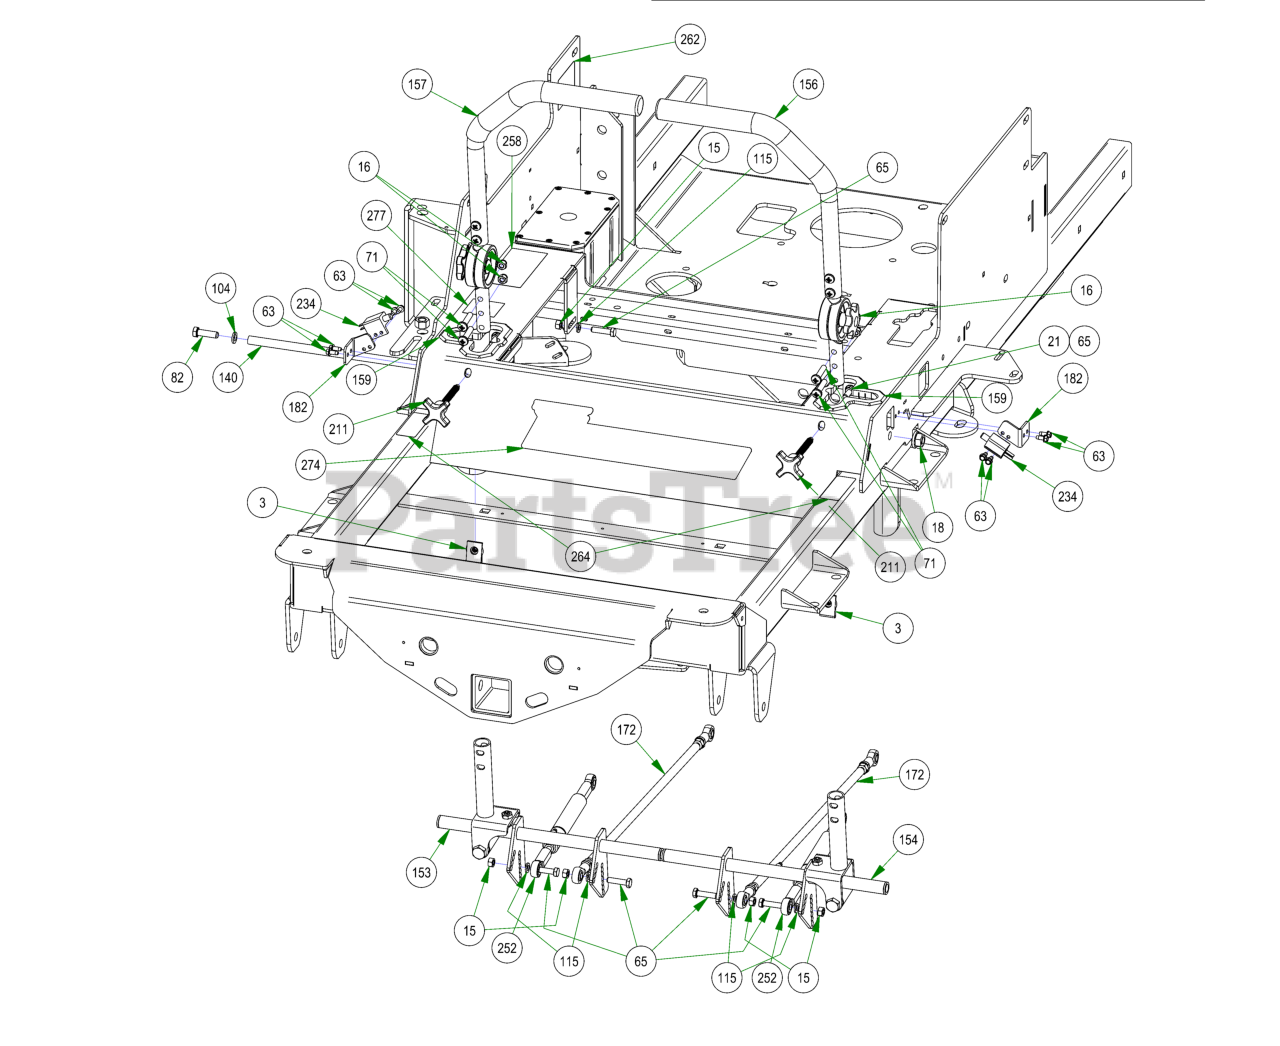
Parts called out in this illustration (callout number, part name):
3	Extruded Nut 3/8"-16 3/4" Hole Center With Patch
11	3/8-16 HEX NUT ZINC
15	5/16-18 HEX NUT ZINC
16	5/16-18 NYL INS L/N ZC
18	1/2-13 NYLON INSERT FLANGE LOCKNUT ZINC
21	5/16-18 HEX SERRATED FLANGE NUT HARD/ZINC
59	5/16-18 x 5/8 Hex Bolt
63	12-24 X 1/2 HEX WASHER UNLSOT F TCS ZINC
65	5/16-18 X 1-1/4 HEX C/S (GR.5) ZC
71	5/16-18 x 1 3/8" Futton Head Torx Drive Bolt
82	3/8-16 X 1-1/4 HEX CAP SCREW (GR.5) ZINC
89	3/8-16 X 1-1/2 HEX CAP SCREW (GR.5) ZINC
104	3/8 SPLIT LOCKWASHER ZINC
112	1/4 USS FLAT WASHER (3/4 OD) ZINC
114	5/16 USS FLAT WASHER (7/8 OD) ZINC
115	5/16 SPLIT LOCKWASHER ZINC
140	2019 Steering Actuator Rod
153	2019 R Series RH Arm Rod Assembly
154	2019 R Series LH Arm Rod Assembly
156	2019 Left Hand ADJ. Steering Arm Kit
157	2019 Right Hand ADJ. Steering Arm Kit
159	Snap-in Drive Arm Bushing
172	2019 Outlaw Gen2 XP Push Rod Assembly
182	2019 Arm Switch Bracket
211	Speed Limiting Knob 3/8-16X 3"
219	2021 LH ROGUE HYDRO TANK LINE ASSY
220	2021 RH ROGUE HYDRO TANK LINE ASSY
230	2021 Rogue Suspension Frame Painted
234	Safety Switch
252	2019 SROID Damper With Spherical Rod Ends
258	2022 EPA Build Date Punch Label
262	Hydraulic Decal
264	2018 LH/RH Steering Control Decal Roll
274	2019 Rogue Cooler Cover Decal
277	2019 Deck Release Decal
